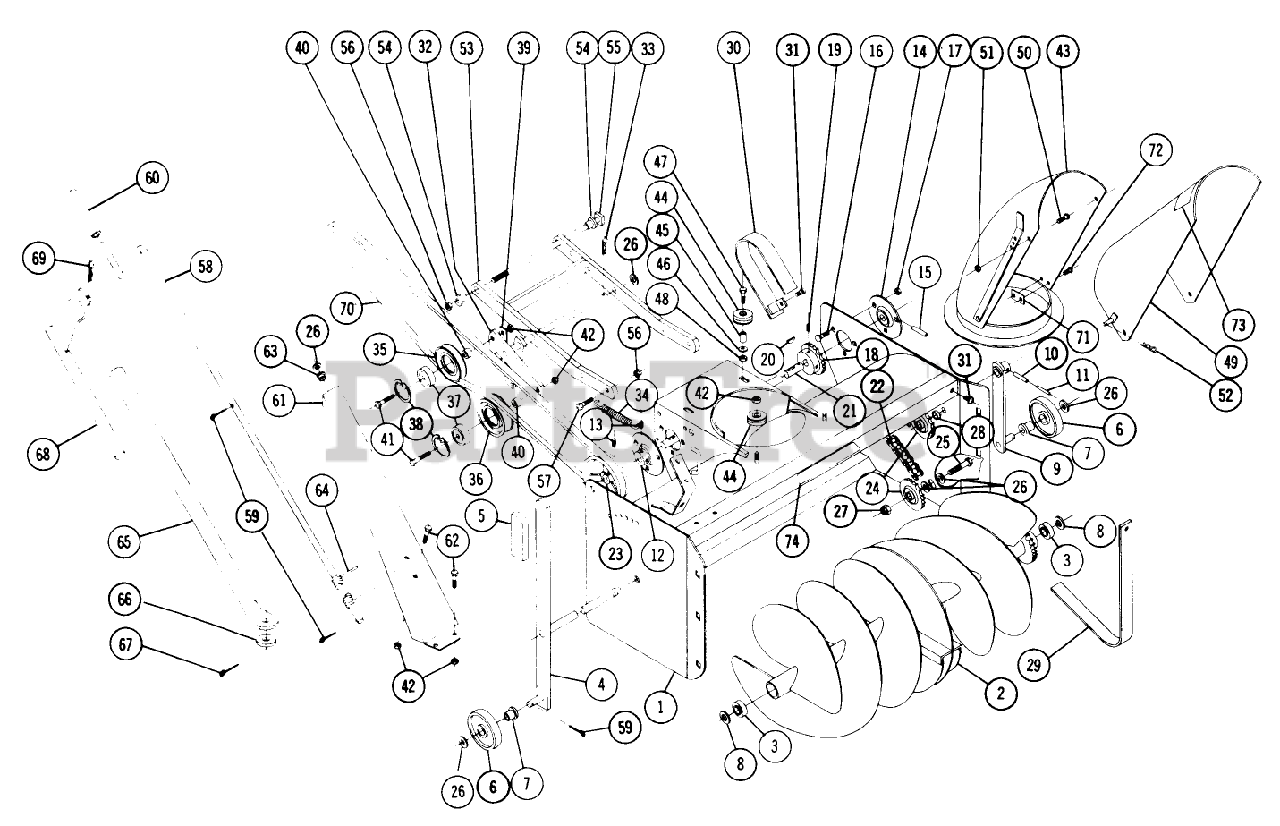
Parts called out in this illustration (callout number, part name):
5	GRIP
10	ROLL PIN 1/4 X 1-1/4
11	Roll Pin 5/32 x 1/4
13	Set Screw 5/16-18 x 5/16
15	PIN-ROLL, SPIROL
16	Bolt Hex 5/16-18 x 3/4
17	Nut-Nylok
18	SPROCKET
19	Set Screw 1/4-20 x 1/4
20	Key
22	CHAIN
25	Bolt-1/2-13-1 3/4
26	Washer
27	Nut-ES 1/2-13
28	SPACER
32	Idler Arm Ass-y
33	Hairpin
34	SPRING *R
37	Bearing-Ball
38	INTERNAL SNAPRING
41	Bolt Hex 3/8-16
42	3/8-16 E.S.
46	Washer
47	Bolt 1/4 20 x 1 1/4
48	Nut-Nylok
50	Bolt Rd. Hd. 1/4-20 x 1/2
51	Nut, 1/4-20
52	Hairpin
55	Bolt-Hex. 3/8-16 x 8 1/2
57	Bolt 3/8-16 x 7/8
59	Cotter Pin
60	Tube
62	Bolt 3/8-16 x 3/4
63	NYLINER BUSHING
66	Washer, 5/8
67	Cotter Pin 3/16 x 1
69	Hairpin
72	Screw #10-16 x 1/2 Self-Tap
